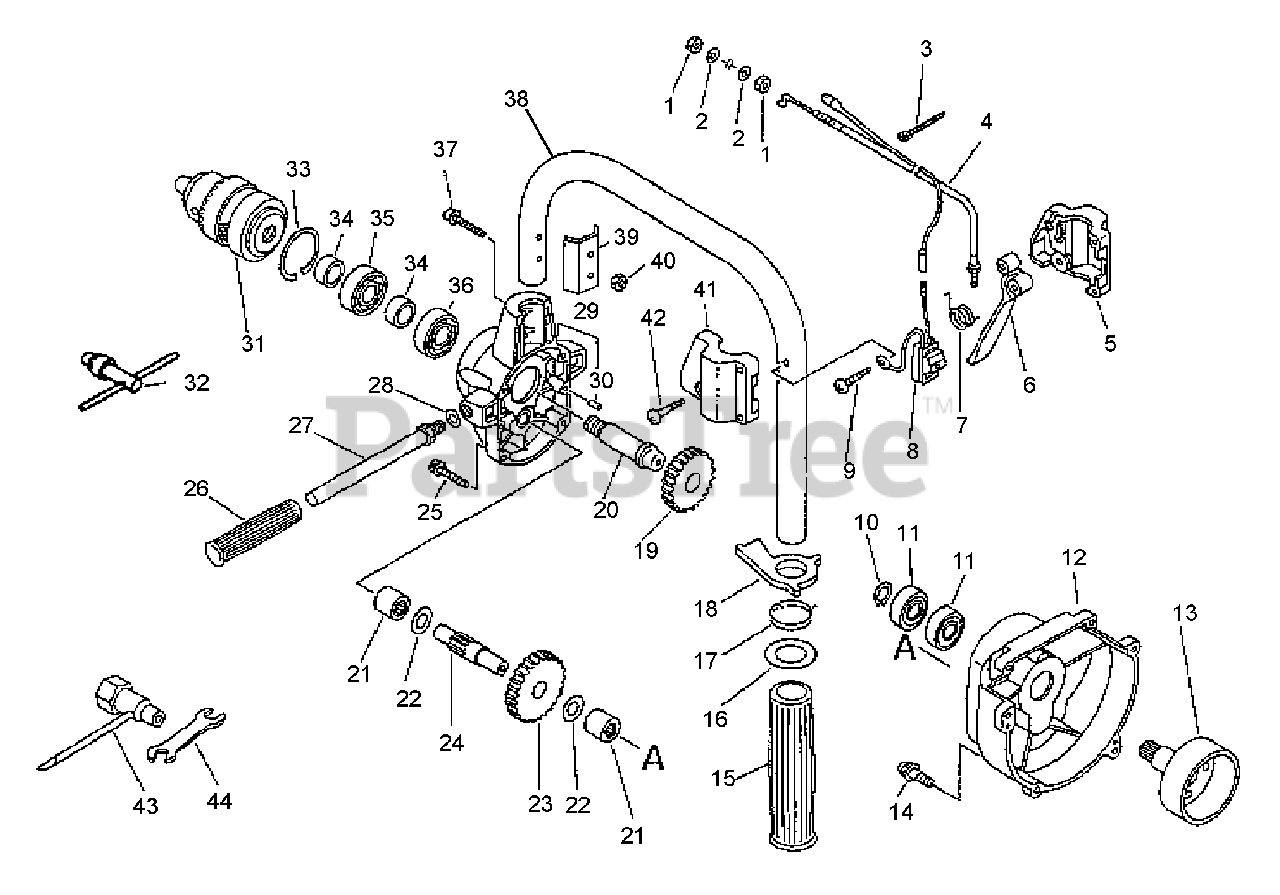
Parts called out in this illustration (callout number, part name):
2	WASHER 6.5×11.5×0.8
3	TIE, CABLE
4	CABLE, THROTTLE
5	BRACKET, THROTTLE CONTROL - RIGHT
6	CONTROL, THROTTLE
7	SPRING, THROTTLE RETURN
8	SWITCH, ON-OFF
9	SCREW 4×30
10	RING, RETAINING - 12
11	BEARING, BALL 6001
12	COVER, FAN
13	DRUM, CLUTCH
14	SCREW 4×16
15	GRIP, HANDLE
16	SPACER
17	SPRING, THROTTLE LOCKOUT
18	LOCKOUT, THROTTLE
19	GEAR, SPUR
20	GEAR, SHAFT
21	BEARING, NEEDLE
23	GEAR, SPUR 56 TOOTH
24	GEAR, SHAFT
25	BOLT 4×25
26	GRIP, HANDLE
27	HANDLE, LEFT
28	WASHER 10.5×18×1.6
29	CASE, GEAR
30	PIN, LOCATING 4
31	CHUCK, KEYED
32	KEY, CHUCK
33	RING, SNAP Ø32
35	BEARING, BALL 6002 DDU
36	BEARING, BALL 6002
37	BOLT M5×35
38	HANDLE ASSY - REAR
40	NUT, LOCK M5
41	BRACKET, THROTTLE CONTROL - LEFT
42	SCREW 4×25
43	T-WRENCH 10×19 MM
44	SPANNER 17×19
